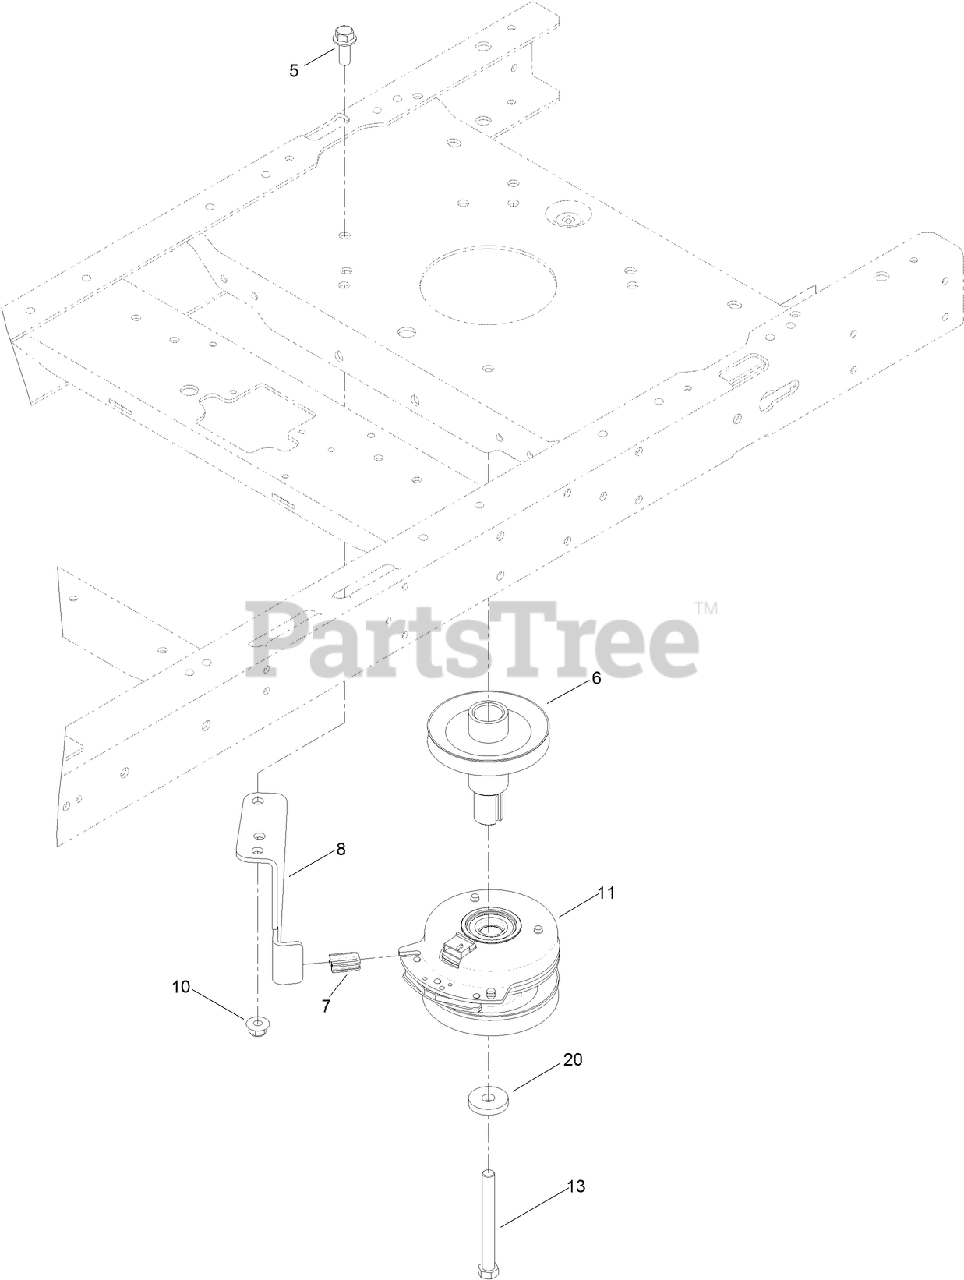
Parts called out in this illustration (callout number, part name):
5	SCREW-HHF
6	PULLEY-ENGINE
7	ISOLATOR-CLUTCH
8	STOP-CLUTCH
10	NUT-HF, NI
11	CLUTCH-PTO
13	SCREW-HH
20	WASHER
